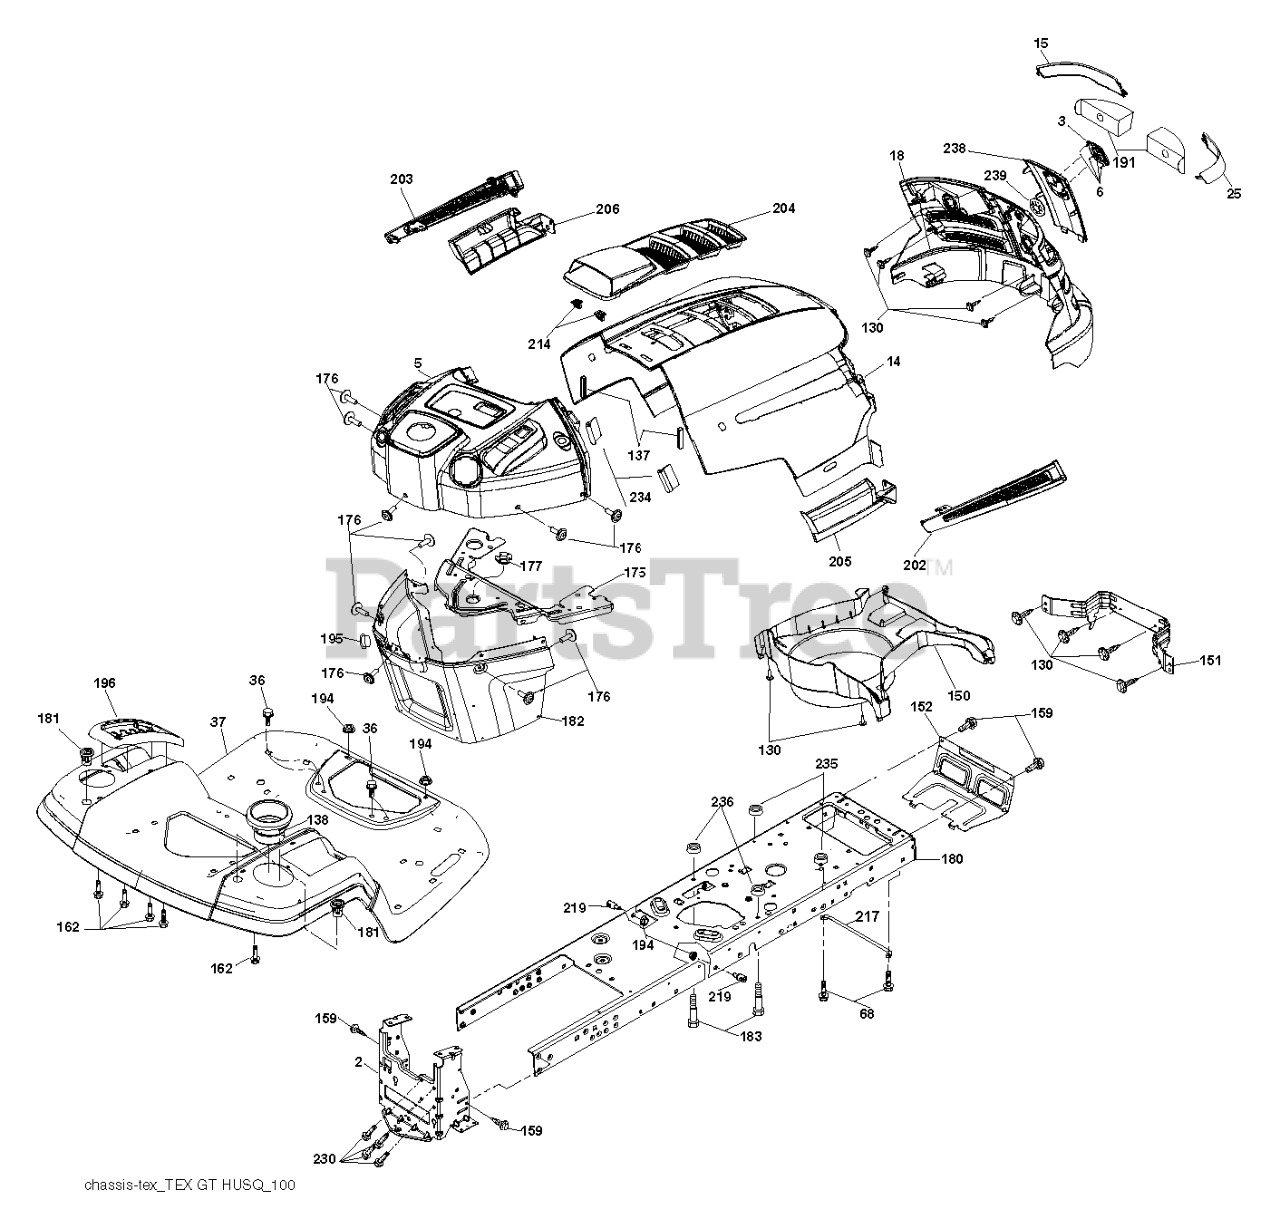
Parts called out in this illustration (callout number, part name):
2	DRAWBAR.1PC.NSTL
3	RP LOGO
5	DASH
14	HOOD
15	LENS.HUSQVARNA LT.LH
18	RP GRILLE/LENS ASM.
25	LENS.HUSQVARNA LT.RH
36	SCREW 3/8-16X3/4
37	FENDER.REAR.ORANGE
68	Screw 5/16-18 x 1/2 Hex, Self Tapping 5/16-18 x 1/2
130	SCREW
137	BUMPER DASH
138	CUPHOLDER.TL.TEX.418
151	BRACKET PIVOT
152	SHIELD.BROWNING/DEBRIS
159	SCREW, 3/8-16X3/4
162	SCREW.HI-LO.CONSOLE
175	CROSSMEMBER
176	SCREW.#10-24X5/8.RN.QU
177	BUSHING STEERING
180	CHASSIS.STAMPING.LT/GT
181	BUSHING.MNT.FEND.CRGO.
182	DASH LOWER
183	BOLT.5/16-18X1-1/4 FULL.THREAD
191	INSERT REFLECTIVE
194	NUT LOCK HEX FLANGE 5/16-18
195	PLUG DASH
196	CONSOLE.ASM.DECK.LIFT.
202	VENT SIDE HOOD RH
203	VENT SIDE HOOD LH
204	VENT TOP HOOD
205	SKIRT SIDE RH
206	SKIRT SIDE LH
214	CLIP.RETAINER.TINNER.
217	ROD PIVOT CHASSIS/HOOD
219	STUD.FASTNER.W/ANTI-ROTATE
230	SHOULDER BOLT 5/16-18TT
234	BUMPER.HOOD.TEX.HUSQVARNA
235	SPACER FENDER
236	NUT.CENTERLOCK.5/16-
238	TRIM
239	NUT PUSH M
